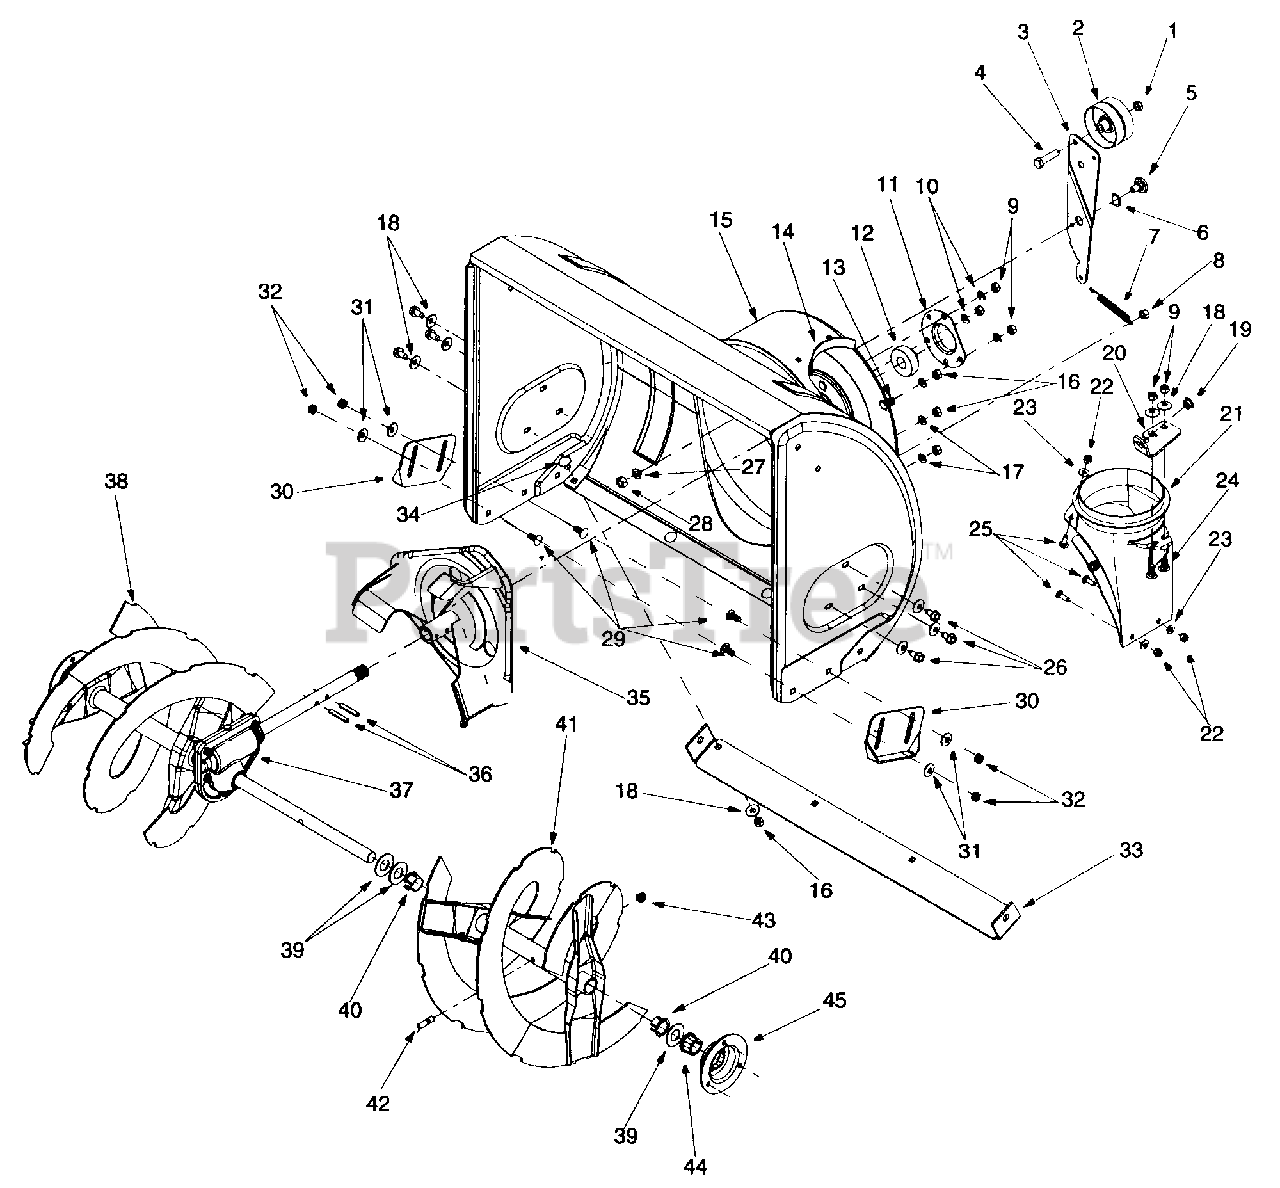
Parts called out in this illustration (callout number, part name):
1	Lock Jam Nut 3/8-24
2	Flat Idler
4	Hex Cap Screw 3/8-24 x 1.50
5	Shoulder Screw
6	Wave Washer
7	Extension Spring
8	Hex Nut 5/16-18
9	Hex Nut 5/16-18
10	Lock Washer 5/16
11	Housing
12	Ball Bearing
13	Carriage Bolt 5/16-18
17	Lock Washer 5/16
18	Bell Washer
19	Bushing
21	Chute Adapter
22	Hex Lock Nut 1/4-20
23	Flat Washer
24	Carriage Bolt
25	Carriage Screw 1/4-20 x .75
26	Hex Washer Screw 5/16-18
27	Lock Washer 3/8
28	Hex Nut 3/8-16
29	Carriage Bolt 5/16-18 x .75
31	Bell Washer
32	Hex Nut 5/16-18
34	Carriage Bolt 5/16-18 x 62
37	24" Gear Assembly
40	Flange Bushing
42	Shear Bolt 5/16-18 x 1.5
43	Lock Nut 5/16-18
44	Hex Flange Bearing
